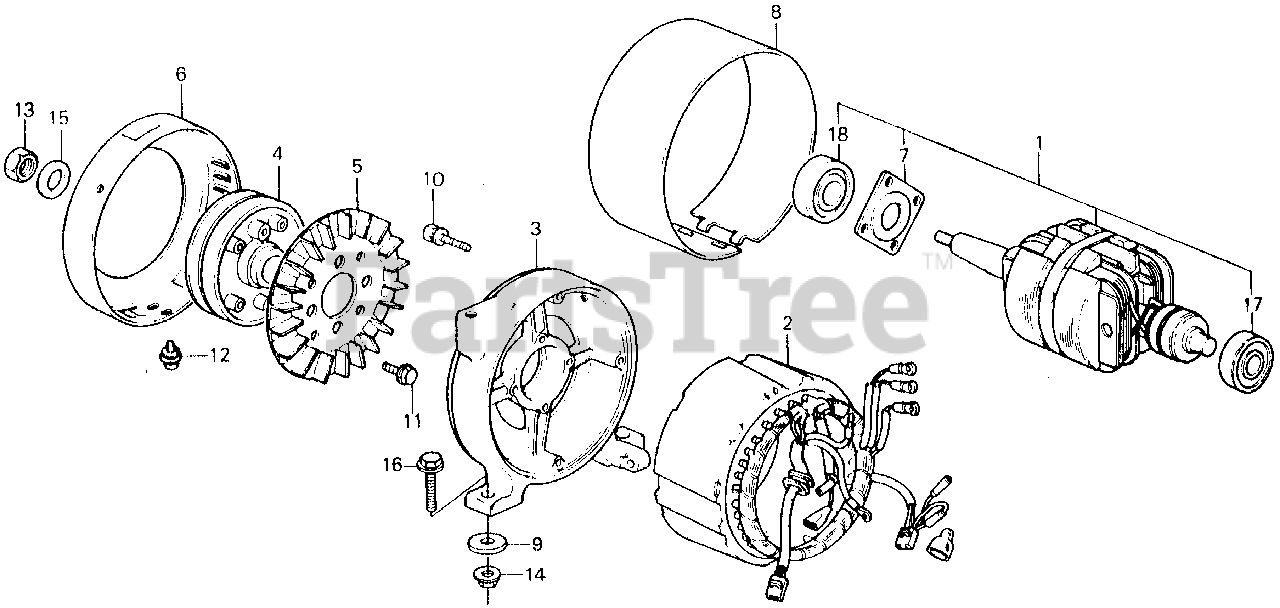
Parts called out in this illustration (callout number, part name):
2	STATOR
2	STATOR ASSY. (NOT AVAILABLE)
3	HOUSING, FR. *NH31* (MCKINLEY WHITE)
4	PULLEY, ALTERNATOR (135MM) *NH1* (BLACK)
6	COVER, FAN *NH31* (MCKINLEY WHITE)
7	PLATE, BEARING SETTING
8	COVER, STATOR *NH31* (MCKINLEY WHITE)
9	WASHER, EX. MANIFOLD
10	BOLT-WASHER (5X20) (NOT AVAILABLE)
11	BOLT-WASHER (6X12)
12	SCREW-WASHER (5X10)
13	NUT, HEX. (18MM) (NOT AVAILABLE)
14	NUT, FLANGE (10MM)
15	WASHER, FLAT (18MM) (NOT AVAILABLE)
16	BOLT, FLANGE (10X32)
17	BEARING, RADIAL BALL (6304UU)
18	BEARING, RADIAL BALL (6306UU) (NOT AVAILABLE)
